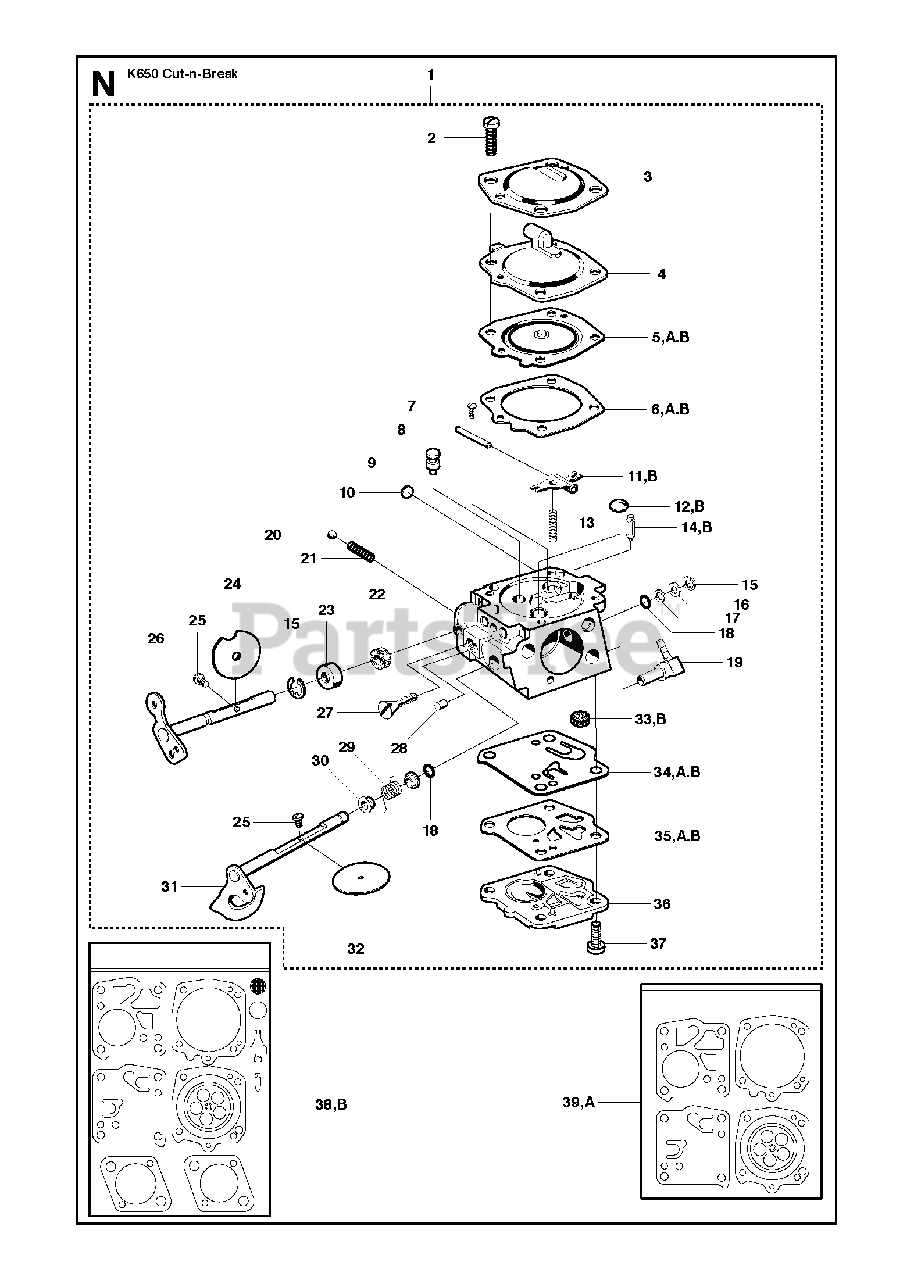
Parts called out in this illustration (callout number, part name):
1	CARBURETTORTillotson HS 175N. Incl. 2 - 39
5	DIAPHRAGMKit 38 & 39
6	DIAPHRAGMKit 38 & 39
7	PIN RETAINING SCREW
8	PIN RETAINING SCREW
9	CHECKVALVE ASSY
15	THROTTLE SH."E"RING
20	CHOKE FRICTION BALL
25	SCREW SHUTTER
27	IDLE SPEED SCREW
28	SPEED SCREW RET BALL
29	THROTTLE SH. SPRING
34	FUEL PUMP DIAPHRAMKit 38 & 39
35	FUEL PUMPKit 38 & 39
36	FUEL PUMP COVER
